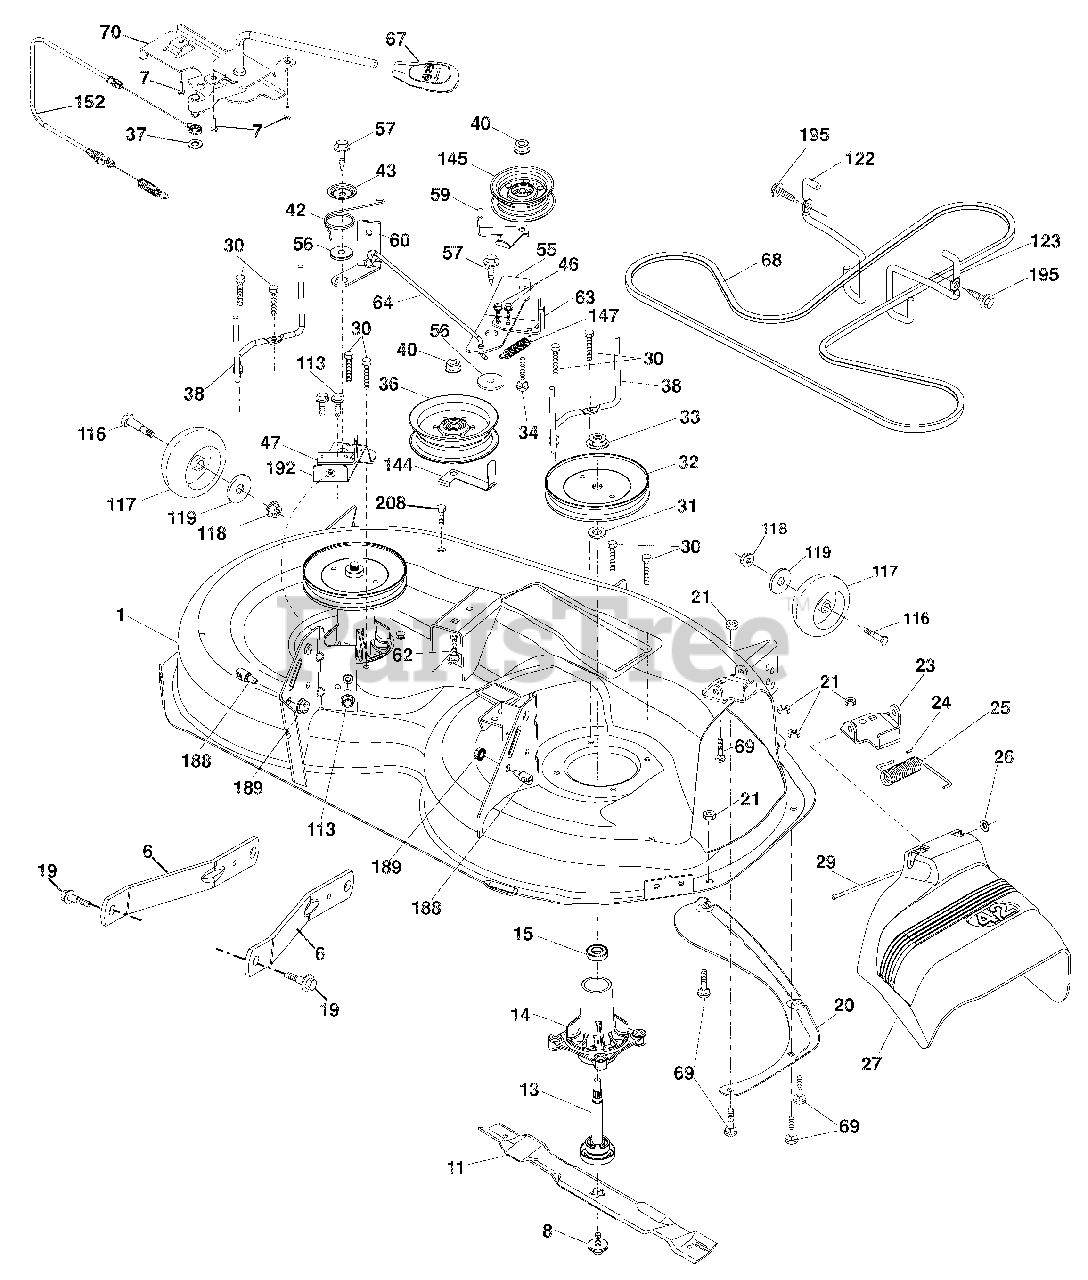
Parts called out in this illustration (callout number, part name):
1	DECK.PNT.WELDMENT.42"
1	DECK.SVC.42"HP.CC.NGWB.TX.431
6	ARM.SUSPENSION.MOWER.REAR.LD
8	BOLT/WASHER ASM.7/16-20.UNF
11	BLADE.MOWER.42"HI LIFT PREMIUM
11	BLADE, HUSQ MULCH KIT
11	BLADE 42" MULCHING PREMIUM
11	Blade 42SP" 3N1
11	Blade 42SP" 3N1 Premium
13	SHAFT ASM.MNDRL.N/GREASEABLE38
14	HOUSING.MANDREL.4PT.SERVICE
15	BEARING.BALL.MANDREL
19	BOLT.SHOULDER
20	BAFFLE.VORTEX.42.STD/HEAVY DTY
21	Nut, Hex, Crownlock 5/16-18
23	BRACKET.DEFLECTOR.38/42"2005
24	CAP.SLEEVE..80X.112.BLK.MOWER
25	SPRING.TORSION.DFL.38/42/46.GR
26	NUT.PUSH.PHOS.& OIL
27	SHIELD.DEFLECTOR.MOWER 42"BLK
29	ROD.HINGE.42/46"
30	SCREW.THD ROLL.DOD PT.HEX
31	WASHER.SPACER.MANDREL
32	PULLEY.MANDREL.5.438 PD.42"
32	MANDREL ASM.SUB.N-GRS.4 BOLT
32	PULLEY/NUT/WASHER AND BLADE BOLT/WASHERS NOT INCLUDED)
33	NUT.FLANGE.LOCK.TOP
34	BOLT.CARR.SH.3/8-16X1-1/2.GR5
36	PULLEY.IDLER.4.50.RAW
37	WASHER.13/32 X 13/16 X 16 GA.
38	KEEPER.BELT.LH.MANDREL.42/46"
40	Nut, Hex, Flangelock 3/8-16
42	SPRING.TORSION.BRAKE
43	SPRING.TORSION.RETAINER
46	SCREW.THD.ROLL.1/4-20 X 5/8
47	BRACKET.CLUTCH.CABLE
55	IDLER.ARM
56	SPACER.RETAINER
57	SCREW.3/8-16X1.SMGML.TAP/R.BLK
59	GUARD.TUV.IDLER
60	ARM.BRAKE.MOWER.42"
62	BOLT.RD.HD.SQ.NK.3/8-16UNC X 2
63	ARM.BRAKE.MOWER
64	LINKAGE.BRAKE
67	HANDLE.CLUTCH.CABLE.LT TEX.428
68	BELT.DRIVE.100.97"
69	BOLT.RDHD.SQNK.5/16-18 X 5/8
70	CLUTCH ASM.MANUAL.LT.TEX
113	BOLT.5/16-18HEX.WHS.HD.LCKSERR
116	BOLT.SHLD."A"2.41."B"1.66
117	WHEEL.GAGE.HALF.SPOKED
118	Nut, Hex, Flangelock 3/8-16
119	Washer 3/8 x 7/8 x 14 Ga.
122	KEEPER.BELT.ENGINE.LH.LT.TEX
123	KEEPER.BELT.ENGINE.RH.LT.TEX
144	KEEPER.BELT.MOWER
145	PULLEY.IDLER 48"PRIMARY
147	SPRING.RETURN
152	CABLE.CLUTCH.MANUAL.W/SPR.
188	STUD.FASTNER.W/'D'ANTI-ROTATIO
189	Nut, Lock Hex Flange 5/16-18 u
192	BRACKET.BRAKE.STAND.LH
195	SCREW.HEXWSH THDR3/8-16X3/4.BL
208	SCREW.THDROL.3/8-16X1/2.TYT.BL
